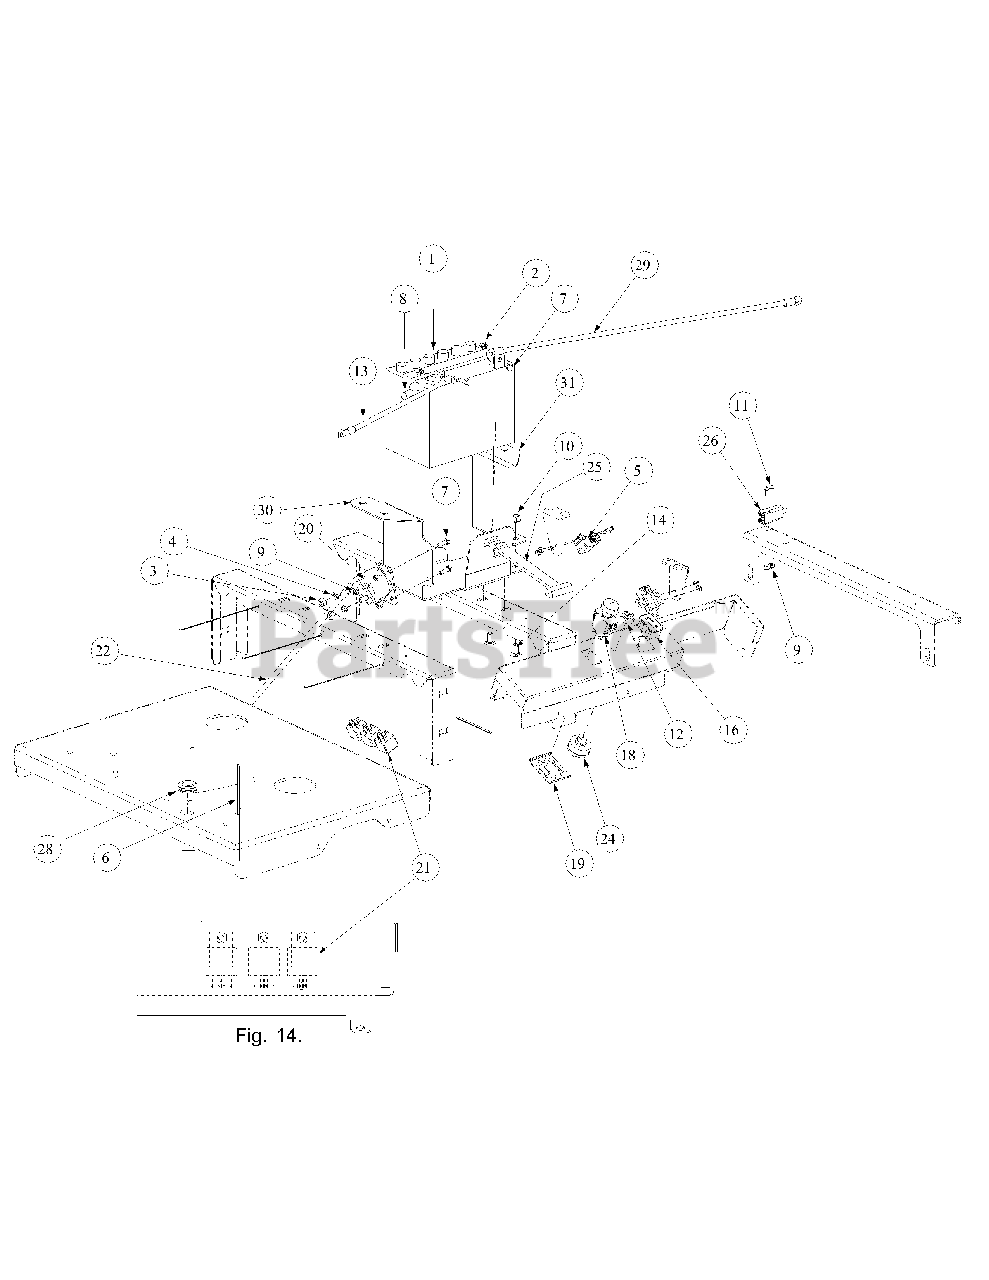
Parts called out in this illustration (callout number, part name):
1	Battery, 12V 375CCA 30 Min
2	Nut, Lock, Nylon Insert, 1/4-20
3	Nylock Nut, 5/16-18
4	Lock Washer, 5/16
5	Switch, Safety
6	Tie, Cable, 3/16 x .05 x 7.4"
7	Screw, Hex, Cap, 1/4-20 x .75
8	Boot, 1" OD Rubber Battery-PST, Red
9	Nut, Lock, Nylon Insert, #10-32
10	Nut, Hex, Flange Lock, 3/8-16
11	Screw, Phillips Head, Machine, 10-32 x 5/8
12	Nut, W/Cap, 5/8-32 Ignition
13	Cable, Battery, Red, 15"
14	Carriage Bolt, 3/8-16 x .75 LG.
16	Meter, Hour
18	Switch, Electric, PTO
19	Bracket, PTO Switch Retainer
20	Solenoid Magnetic Switch
21	Relay, 12V 40A
22	Cable, Battery Red, 32"
24	Switch, Ignition, 6 Pin
25	Strap, Battery
26	Switch, Plunger
28	Grommet, .75 ID
29	Cable, Battery Red, 24"
30	Mount Bracket, Battery
31	Mount Bracket, Battery
